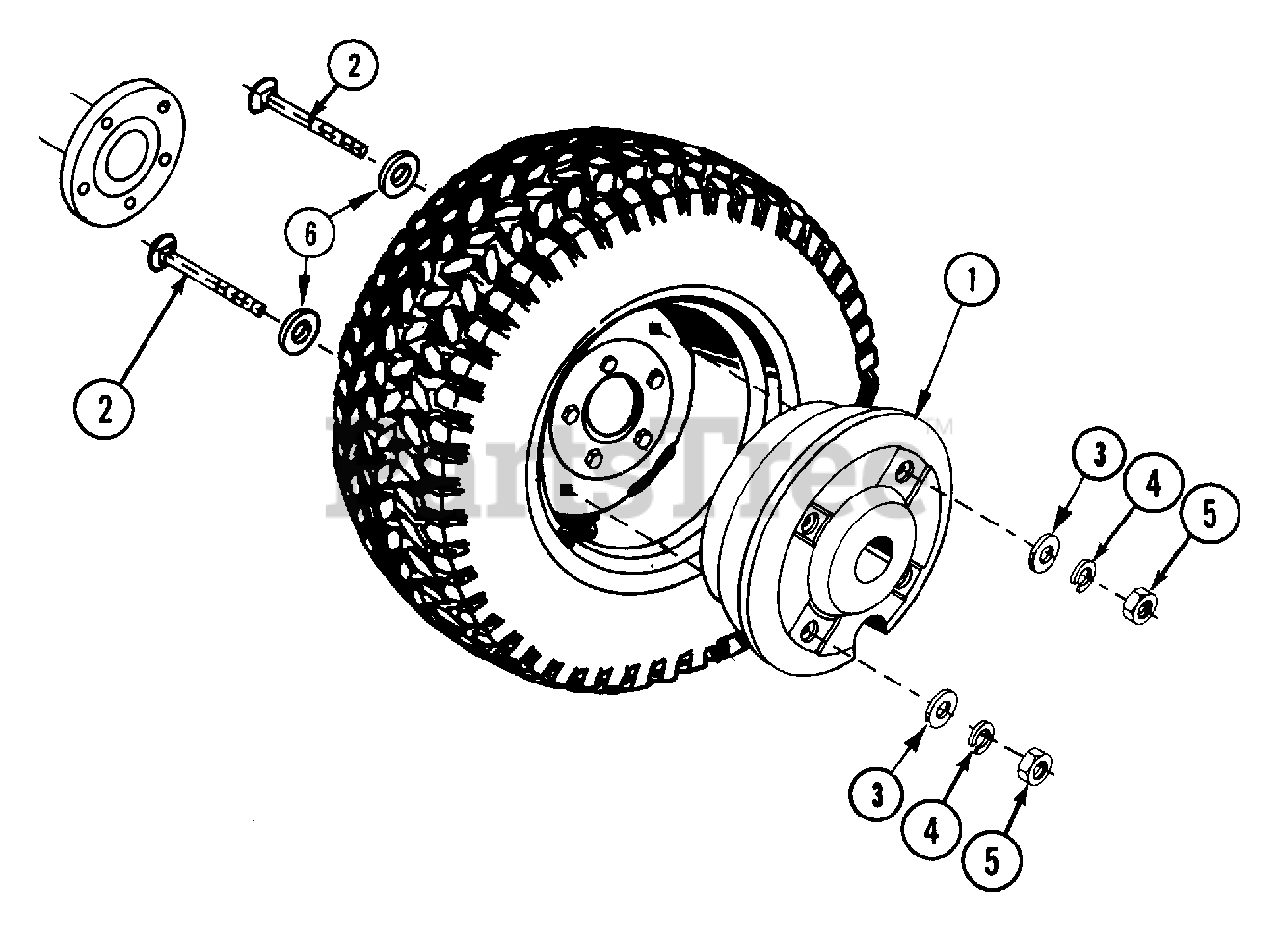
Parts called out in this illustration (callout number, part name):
1	WHEEL WEIGHT 50 LB
2	@BLT-RDHDSQNK .50-13X8.50 G5YZ
3	WSHR-FL-STL .531X1.062X.095 PL
4	WSHR-LK .500X.151 HVY PL
5	NUT .50-13 PL
6	GROMMET .438ID X .688 OD
